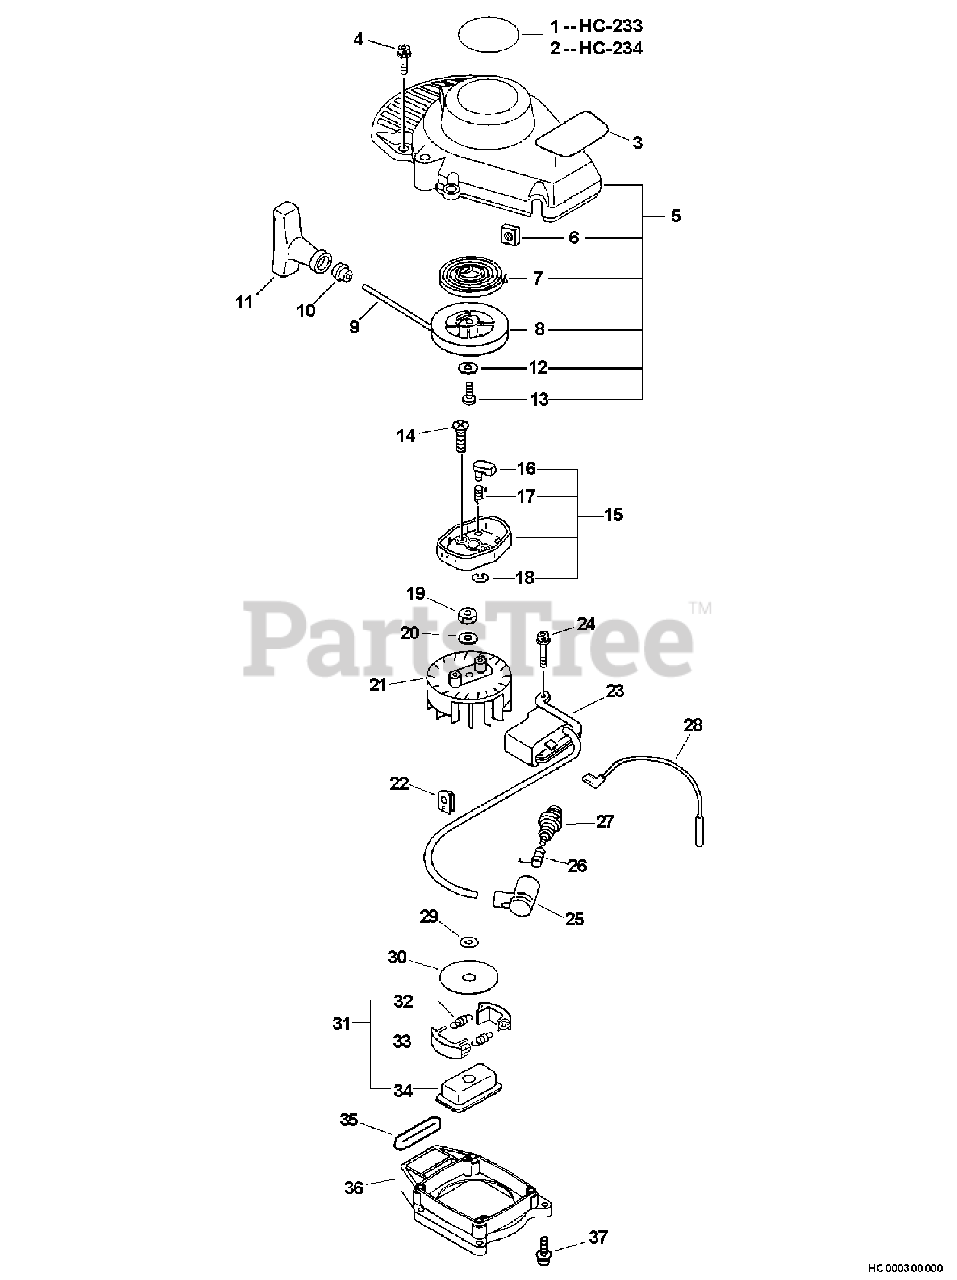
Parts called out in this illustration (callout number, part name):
1	LABEL, MODEL
2	LABEL, MODEL
3	LABEL, CAUTION - ISO
4	BOLT 5×16
5	STARTER, RECOIL
6	NUT M5
7	SPRING, RECOIL
8	REEL, ROPE
9	ROPE, STARTER 3.0×1000
10	GUIDE, ROPE
11	GRIP, STARTER
12	WASHER
13	SCREW
14	SCREW 6×14
15	PULLEY ASSY, STARTER
16	PAWL, STARTER
17	SPRING, RETURN
18	E-RING 4
20	WASHER 8.5×16×1.2
21	FLYWHEEL
23	COIL, IGNITION
24	BOLT 5×16
25	CAP, SPARK PLUG
26	TERMINAL, SPARK PLUG
27	SPARK PLUG - BPM-7Y
28	LEAD - IGNITION 145 MM
29	WASHER
30	PLATE, CLUTCH
31	CLUTCH ASSY
32	SPRING, CLUTCH
33	SHOE, CLUTCH
34	HUB, CLUTCH
35	CUSHION, FUEL TANK
36	CASE, CLUTCH
37	BOLT 4×14
